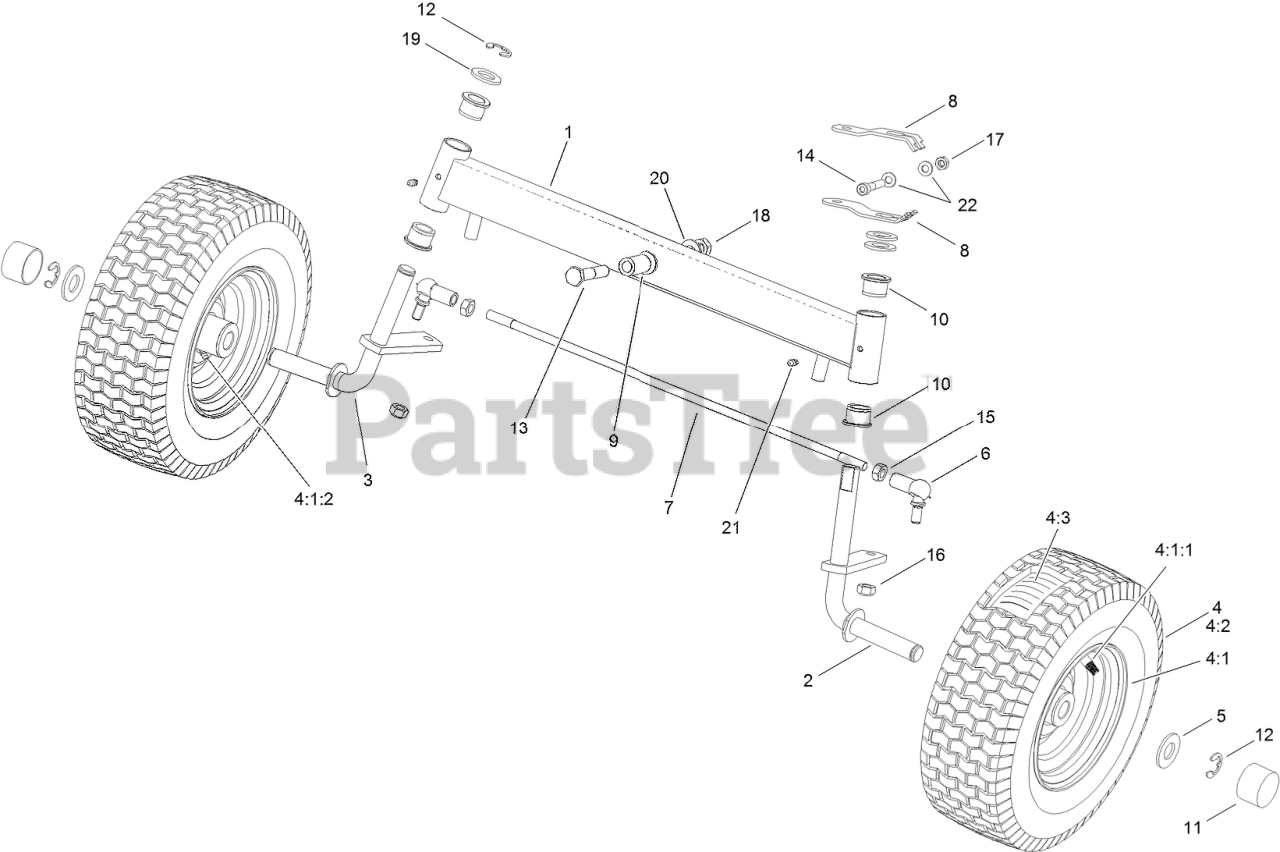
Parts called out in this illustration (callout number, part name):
1	FRONT AXLE ASM
2	SPINDLE-LH
3	SPINDLE-RH
4	WHEEL ASM
4:1	FRONT RIM ASM
4:1:1	Valve-Tire
4:1:2	FITTING-GREASE
5	WASHER
6	JOINT-BALL, ANGLE
7	TIE ROD-AXLE, FRONT
8	LEVER-SPINDLE, STEERING
9	SPACER
10	BUSHING-SWIVEL
11	CAP-HUB
12	CLIP-SPRING
13	SCREW-HH
15	NUT-HEX
16	NUT-LOCK, NI
17	NUT-LOCK, NI
18	NUT-LOCK, HEX NI
19	WASHER-FLAT
20	WASHER
21	FITTING-GREASE
22	WASHER-PLAIN
